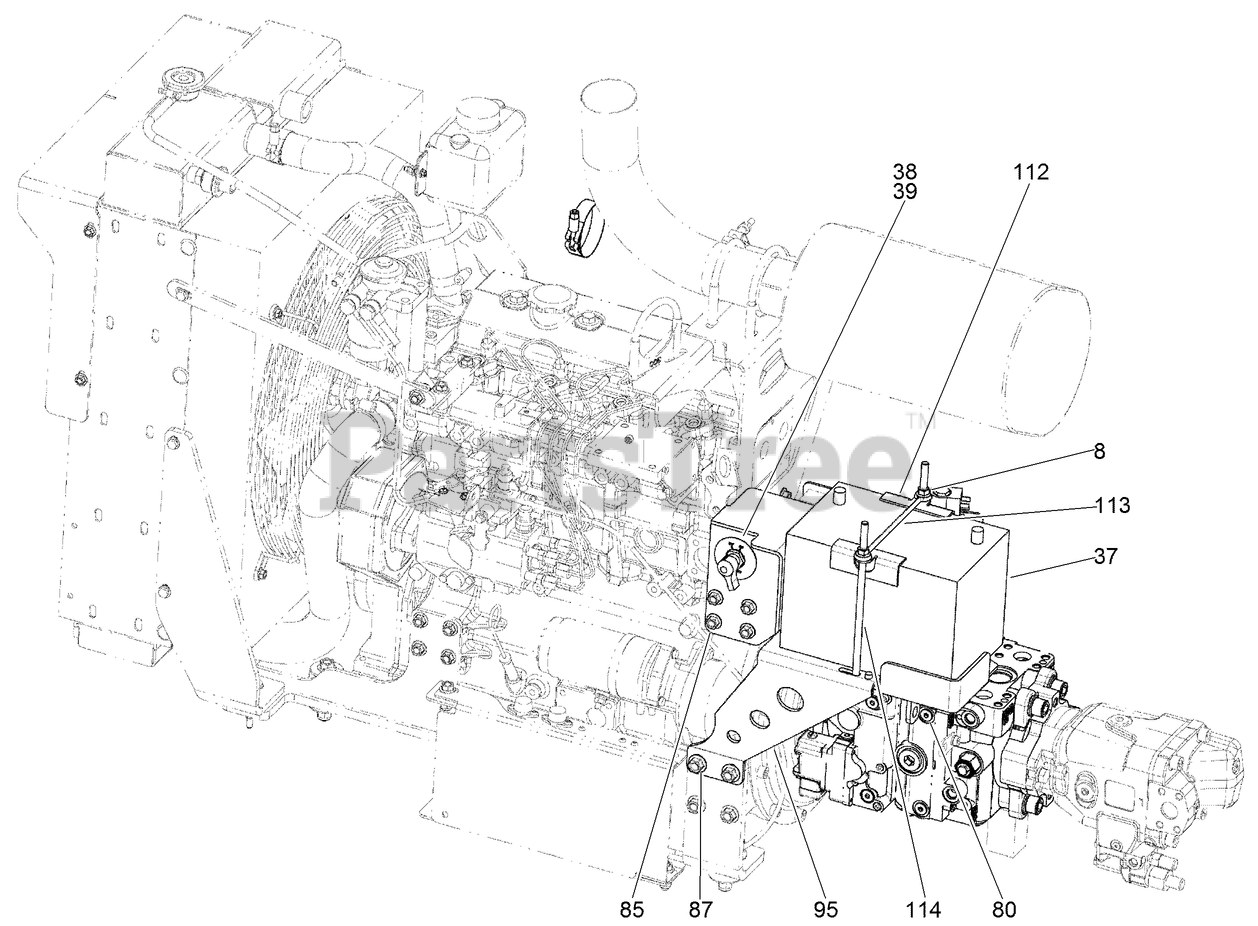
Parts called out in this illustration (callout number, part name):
8	NUT-Serr Flg 3/8-16 UNC GR5 ZND
37	BATTERY - 12VDC (obtain from local dealer)
38	SWITCH-BATTERY (1000 AMP)
39	FACEPLATE-BATTERY, ON/OFF
80	NUT-FLANGE, NYLOCK
85	SCREW-FLANGE
87	SCREW, METRIC FLANGE w/BODY-M12 x 30
95	ASSEMBLY - Battery Mount
112	ANGLE-HOLDDOWN, BATTERY
113	BRACKET-HOLDDOWN, BATTERY
114	BOLT-HOLDDOWN, BATTERY
